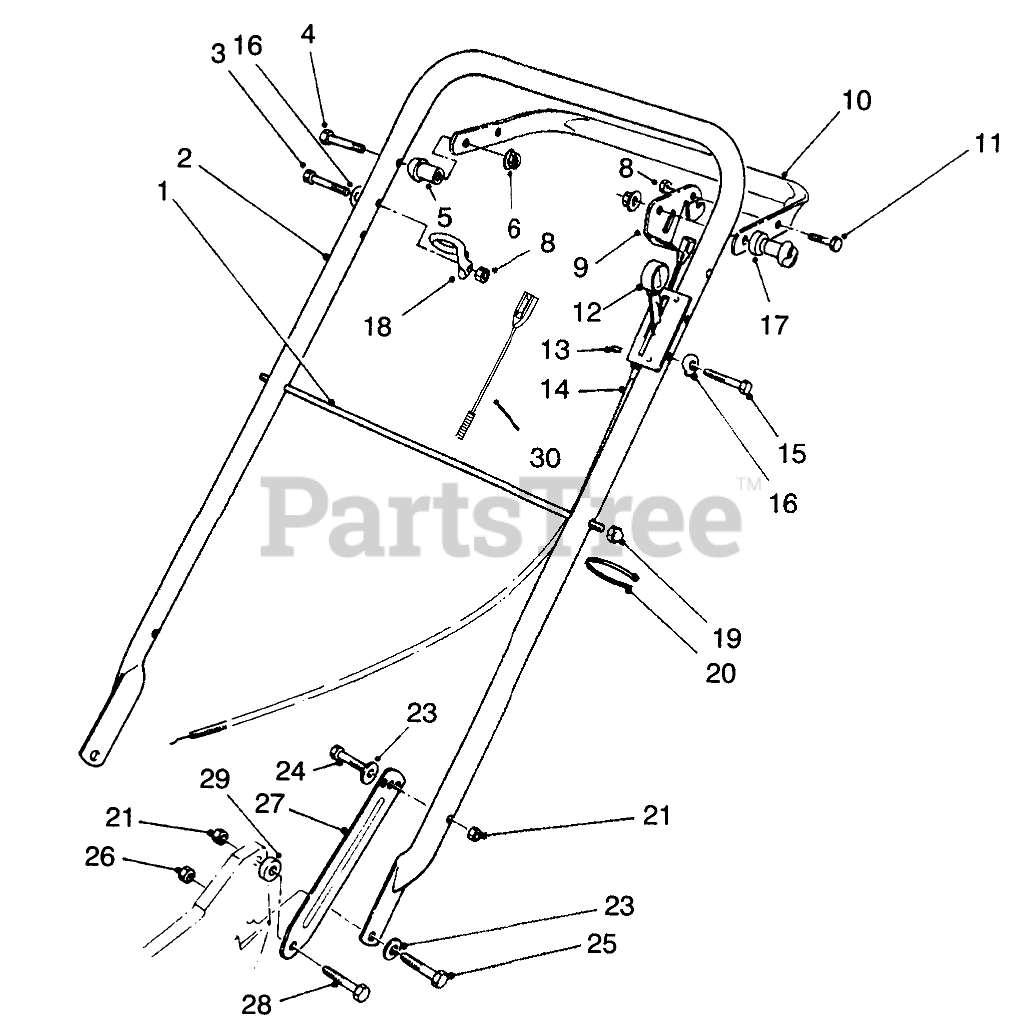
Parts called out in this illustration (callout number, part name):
1	ROD-SUPPORT, BAG
2	Handle
3	SCREW-HH
4	SCREW-HH
5	SPACER-SUPPORT
6	NUT-LOCK, NI
8	NUT-LOCK, NI
9	LEVER-CONTROL
10	Bar-Control
11	SCREW-HH
12	CONTROL-THROTTLE
13	E-RING
14	CABLE - THROTTLE
15	SCREW-HH
16	WASHER
17	SPACER-NYLON
18	GUIDE-ROPE
19	NUT-CAP
20	TIE-CABLE
21	NUT-LOCK, NI
23	WASHER-BELLEVILLE
24	SCREW-HH
25	SCREW-HH
26	NUT-LOCK, NI
27	Latch-Handle
28	SCREW-SHOULDER
29	SPACER
30	CABLE - BRAKE
